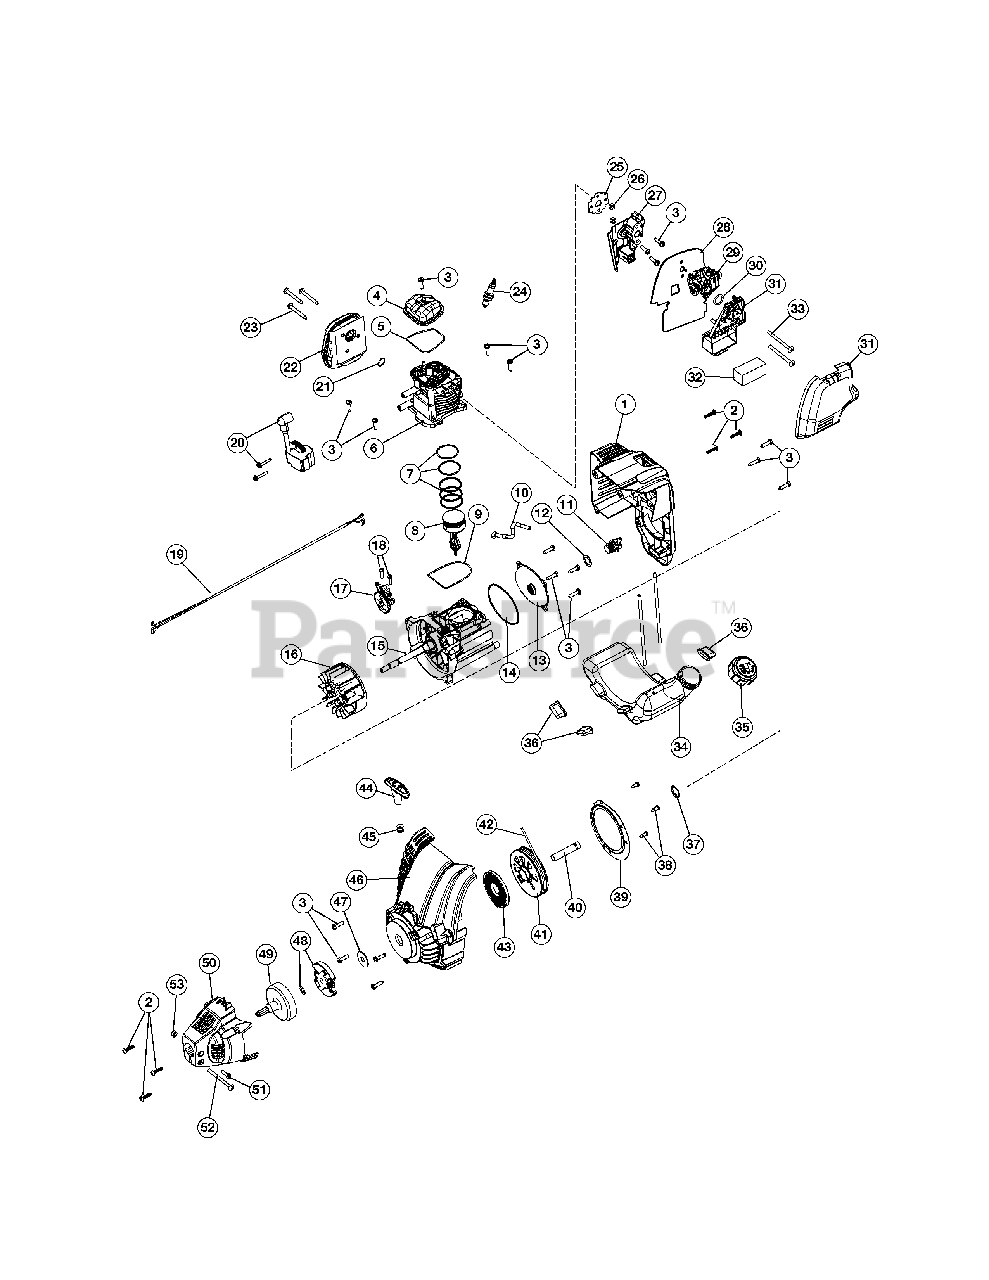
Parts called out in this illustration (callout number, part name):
1	Engine Cover Assembly
2	Cover Screw
3	Screw
4	Rocker Cover
5	Rocker Cover O-Ring
6	Cylinder Assembly
7	Piston Ring Assembly
8	Piston Assembly
9	Cylinder O-Ring
10	Breather Hose
11	Oil Plug
12	Oil Plug O-Ring
13	Crankcase Cover
14	Crankcase Cover O-ring
15	Crankcase Assembly
16	Flywheel Assembly
17	Cam Bracket Assembly
18	Cam Bracket Screw
19	Lead Wires
20	Module Assembly
21	Muffler Gasket
22	Muffler Assembly
23	Muffler Screw
24	Spark Plug
25	Insulator Gasket
28	Carburetor Gasket
29	Carburetor
31	Air Cleaner Cover Assembly
32	Air Filter
34	Fuel Tank Assembly w/Fuel Lines
36	Fuel Tank Pads
38	Pressure Plate Screw
39	Pressure Plate
41	Starter Assembly
42	Rope
43	Recoil Spring
44	Handle
46	Starter Housing Assembly
48	Clutch & Clutch Washer
49	Clutch Drum
50	Clutch Cover
51	Anti-Rotation Screw
52	Clamp Screw
